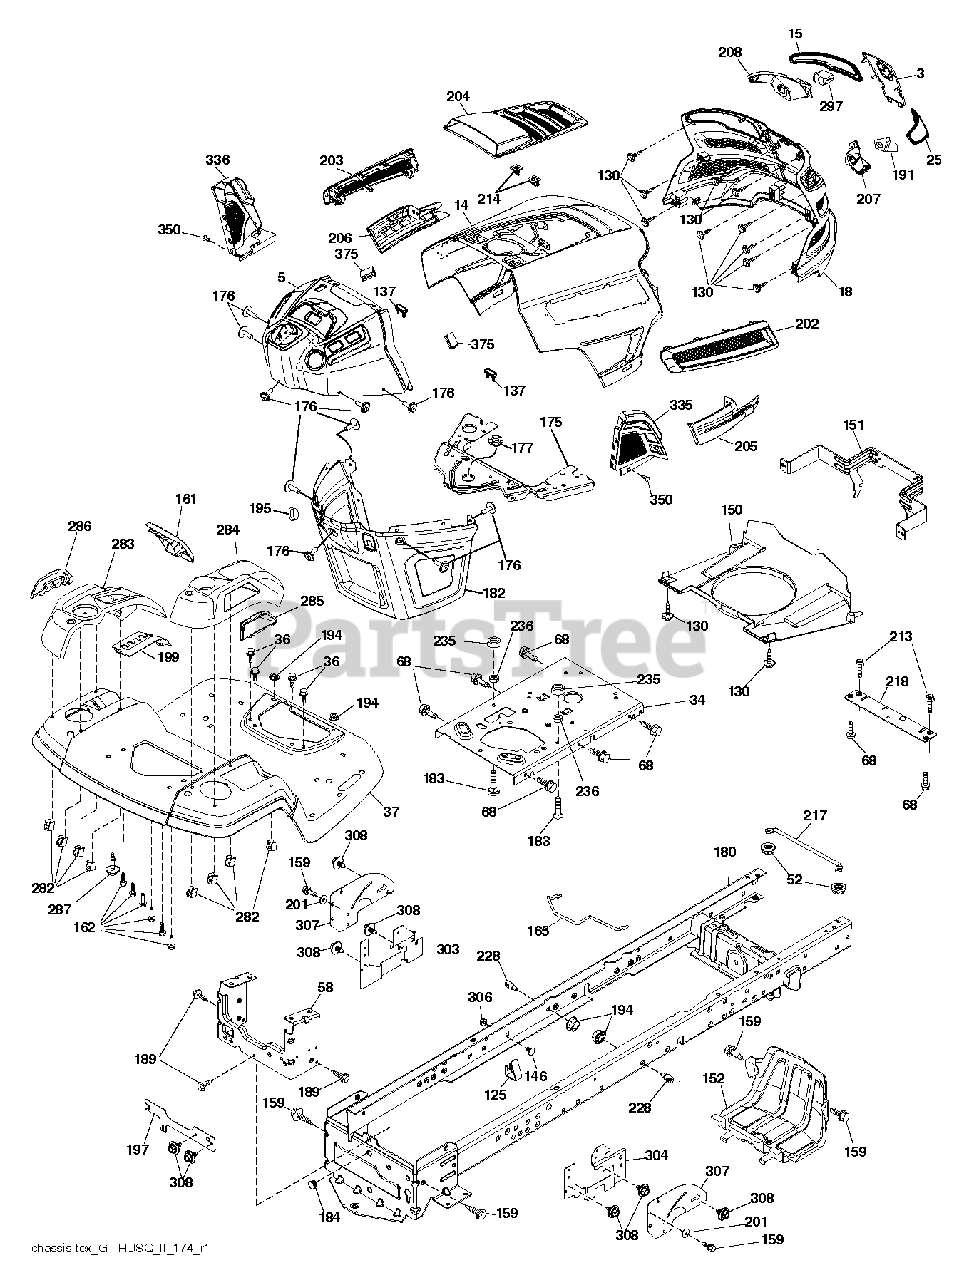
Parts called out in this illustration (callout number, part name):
3	APPLIQUE.SUBASM.GT.HUSQ.II
5	DASH.UPPER.GT2.SM.E.RS.CH.498
14	HOOD.ASM.HUSQVARNA.GT.TEX.ORAN
15	LENS.HEADLIGHT.LH.GTII.2011
18	GRILLE.SUBSTRATE.2011.
25	LENS.HEADLIGHT.RH.GTII.2011
34	PLATE.ENGINE.WELDED.CHASSIS
36	SCREW 5/16"
37	FENDER.TLT.FS.W/CPH.W/FW.668
52	LOCKNUT
58	DRAWBAR UPPER 2PC SMALL FENDER
68	SCREW LT
125	CLIP.FUEL.LINE
130	SCREW.#10 X 0.750.BOS
137	BUMPER DASH
146	BOLT.RDHD.SHT.SQNK.3/8-16X5/8
150	AIR.DUCT.GTV.BLACK
151	BRACKET.PIVOT.HOOD.GT.HUSQ.II
152	SHIELD.BROWNING.PNT.GT.V2
159	SCREW, 3/8-16X3/4
161	WINDOW.FUEL.LT.TEX.GREY
162	SCREW.HI-LO.CONSOLE
165	SUPPORT.TANK.REAR.W/TEX
175	PLATE.CROSSMEMBER.HUSQ
176	SCREW.#10-24X5/8.RN.QU
177	BUSHING, STEERING
180	CHASS.WLDMNT.TLT.12GA/2PC.20"
182	DASH LOWER.HUSQ.PRED NO CRUISE
183	BOLT.5/16-18X1-1/4 FULL THD
184	PLUG.DEMO.625
189	SCREW
191	INSERT.REFLECTIVE.RH.HUSQ.GTII
194	NUT LOCK HEX FLANGE 5/16-18
195	PLUG.HOLE.DASH.LOWER.12V.BLK
197	SHIELD.DRAWBAR.LT.REAR.TANK
199	PLATE.DECK.LIFT.HUSQ.LT
201	WASHER
202	VENT.SIDE.RH.GT.HUSQ.II.
203	VENT.SIDE.LH.GT.HUSQ.II.498
204	VENT.TOP.HUSQ.GT2
205	SIDE.TRIM.RH.GT.HUSQ.II
206	SIDE.TRIM.LH.GT.HUSQ.II.GRAY
207	BEZEL LIGHT.RH.GT.II.MYLAR
208	BEZEL LIGHT.LH.GT.II.MYLAR
213	BOLT
214	CLIP.RETAINER.TINNER.
217	ROD.PIVOT.HOOD
218	X-PIECE.HOOD.STOP.NON/
228	STUD.FASTNER.W/ANTI-ROTATE
235	SPACER FENDER
236	NUT.CENTERLOCK.5/16-
282	CLIP.RETAINER.CONSOLE.LT.HUSQ
283	CONSOLE.ASM.LFT.RSF.HUSQ.LT
284	CONCOLE.CNTRL.PDL.HUSQ.LT.498
285	CONSOLE INSERT RH
286	CONSOLE.INSRT.LH.HUSQ.LT.BLACK
287	SCREW 1/4X20
297	INSERT.REFLECTIVE.LH.HUSQ.GTII
303	SHIELD.LOWER.LH/LT/GT/BLK.EDIP
304	SHIELD.RH.LOW.LTGT.NO
306	NUT LOCK FLG 3/8-16 UNC
307	SHIELD.UPPER.LT.GT.ISO
308	BOLT, 5/16-18 X 1 3/4
335	COVER.LOWER.DASH.RH.BLACK
336	COVER-LH.LOWER.DASH.GT2.BLACK
350	CLIP.X-MAS.TREE
375	BUMPER CLIP-ON. DASH 1"
